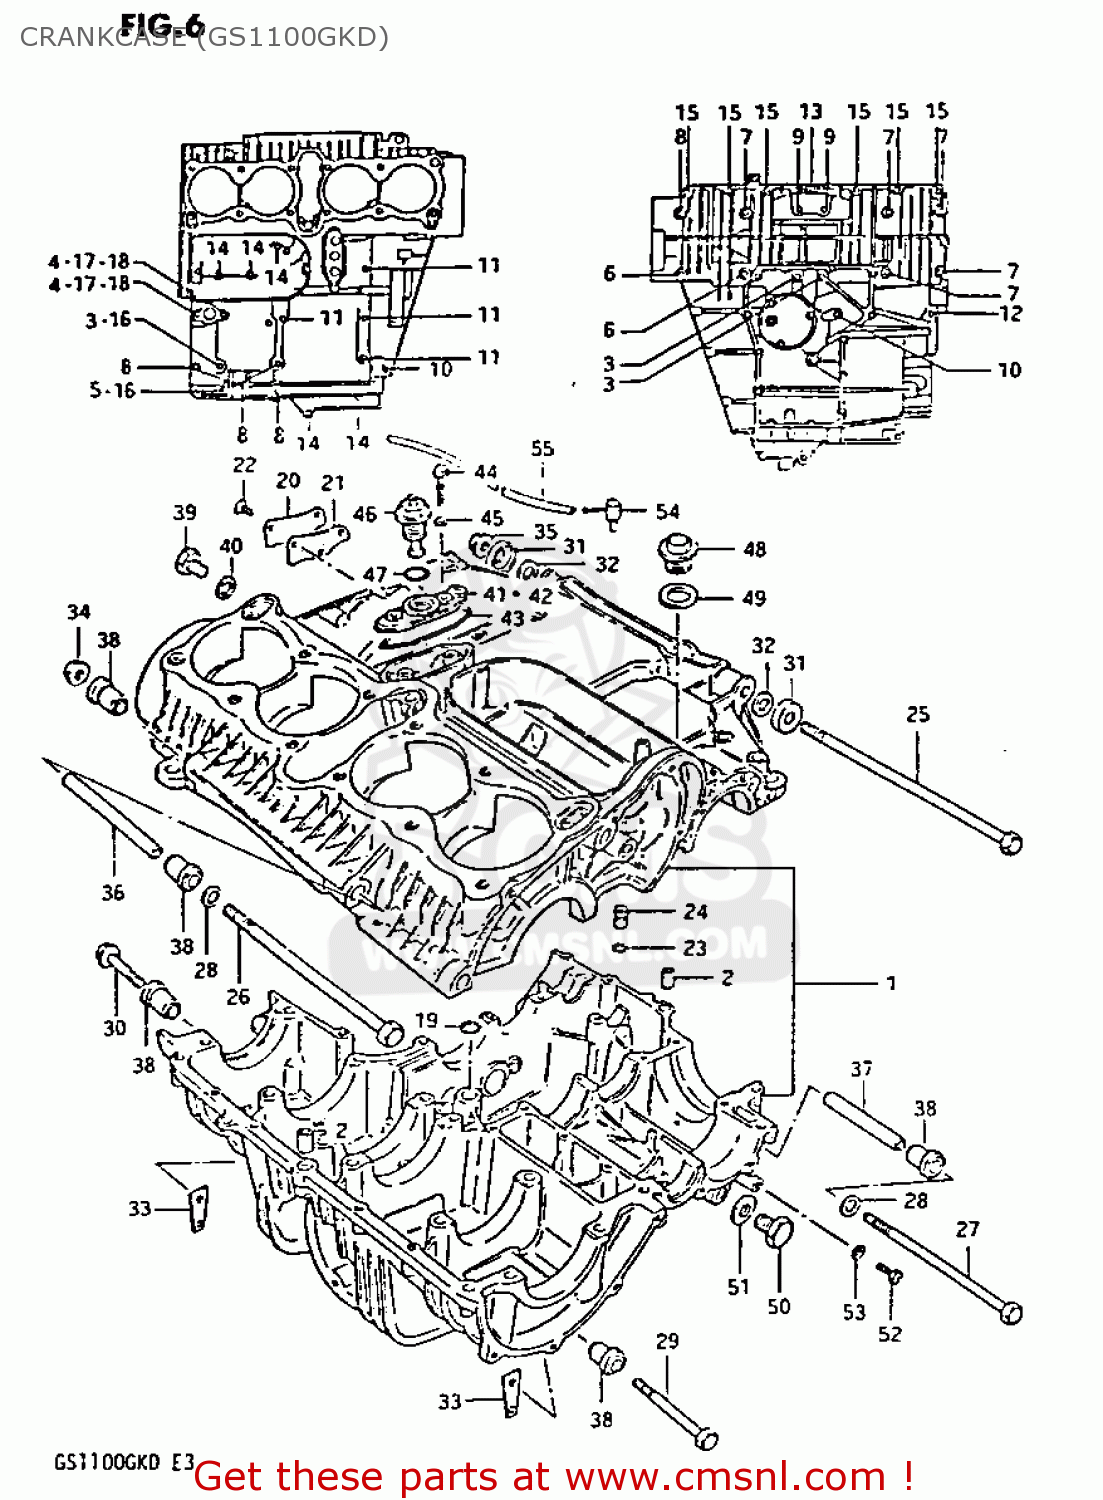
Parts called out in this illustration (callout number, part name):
1	CRANKCASE SET
2	PIN
3	BOLT(8X125)
4	BOLT 8X110
5	BOLT
6	BOLT
7	BOLT (8X90)
8	BOLT (8X65)
9	BOLT 8X60
10	BOLT (6X90)
11	BOLT (6X75)
12	BOLT 6X55
13	BOLT 6X50
14	BOLT (6X45)
15	BOLT 6X35
16	NUT 8MM
17	NUT
18	GASKET 8.2X14X1 (NAS)
19	O RING(D:3.2,ID:12.9)
20	CAP,OIL GALLERY
21	GASKET,OIL GALLERY CAP (NAS)
22	SCREW
23	O RING(D:1.05,ID:3.1)
24	UNION
25	BOLT
26	BOLT 10X250
27	BOLT
28	WASHER 10MM
29	BOLT
30	BOLT 10X55
31	WASHER
32	WASHER(10.5X20X3.2)
33	NUT
34	NUT
35	NUT 10MM
36	SPACER
37	SPACER
38	BUSH
39	PLUG(14X12)
40	GASKET(14X19.2X2) (NAS)
41	HOUSING,OIL PRESSURE SWITCH
42	HOUSING,OIL PRESSURE SWITCH
43	O RING,PRESSURE SWITCH HOUSING
44	BOLT
45	GASKET(5.8X13X1.2) (NAS)
46	SWITCH ASSEMBLY
47	O RING(D:1.9,ID:18.8)
48	PLUG
49	GASKET
50	PLUG
51	GASKET(14X19.2X2) (NAS)
52	SCREW(6X10)
53	GASKET(5.8X13X1.2) (NAS)
54	BPLUG,BEVEL GEAR BREATHER
55	HOSE
